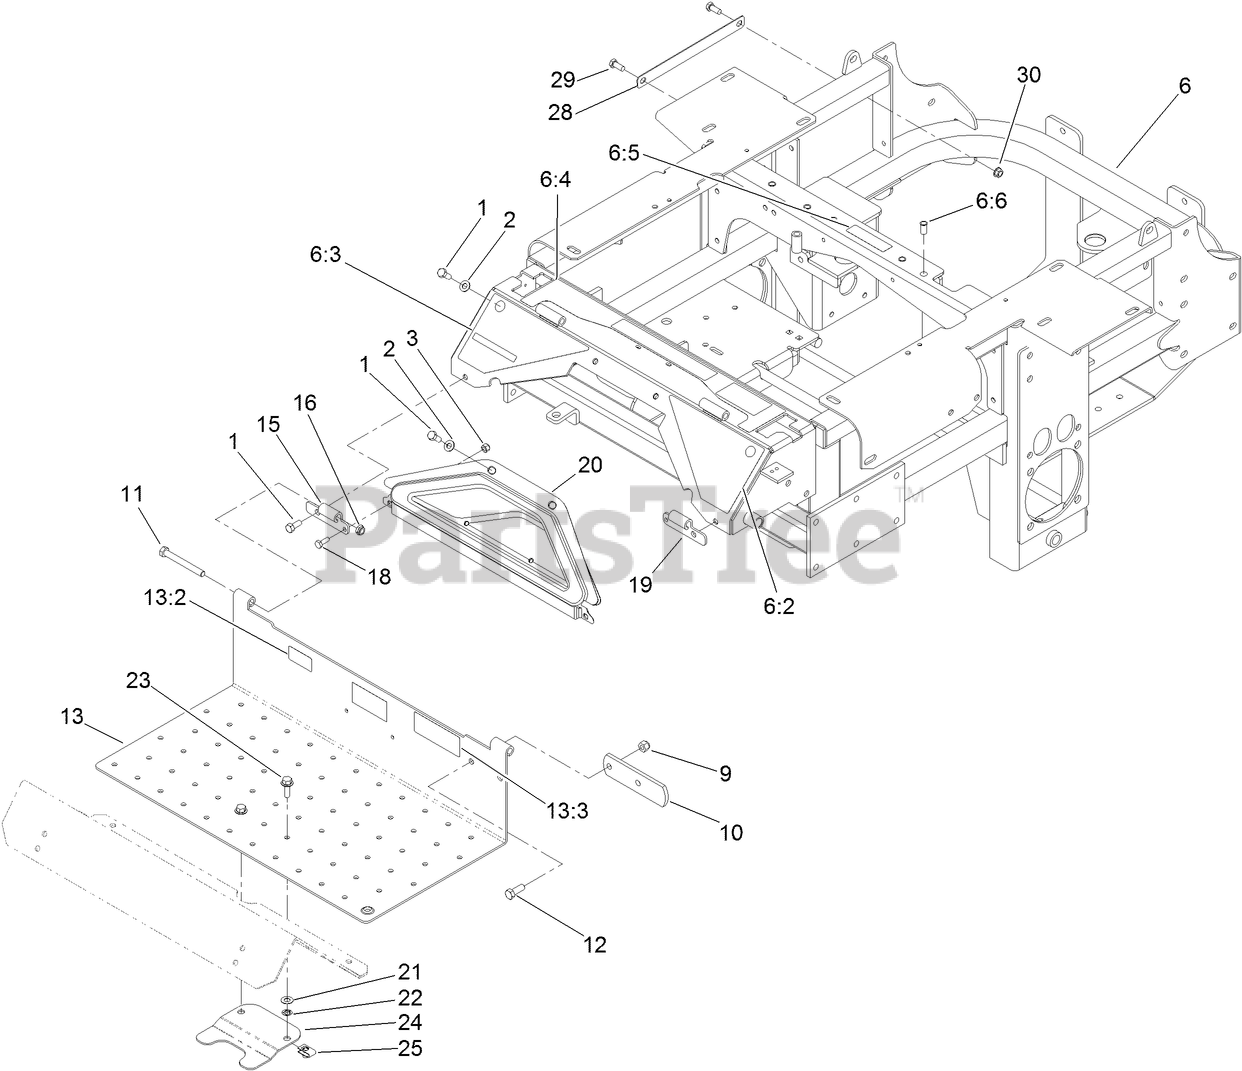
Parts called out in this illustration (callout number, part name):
1	SCREW-HH
2	WASHER-FLAT
3	NUT-LOCK, NI
6	TRACTION FRAME ASM
6:2	DECAL-DANGER, LEFT
6:3	DECAL-WARNING, RIGHT
6:4	DECAL-CONSOLE, TOP (CE)
6:5	DECAL-COVER, MISSING
6:6	NUT-CLINCH
9	NUT-LOCK, NI
10	STOP-BRAKE, PARK
11	SCREW-HH
12	SCREW-HH
13	FLOOR PAN ASM
13:2	DECAL-PROTECTION, EAR
13:3	DECAL-DIESEL, BIO-READY
15	HINGE-FLOORPAN, LH
18	SCREW-HH
19	HINGE-FLOORPAN, RH
20	POCKET
21	WASHER-THRUST
22	NUT-PUSH
23	SCREW-HHF
24	ADAPTER-CAPTIVE
25	NUT-U
29	SCREW-HH
30	NUT-HHF, WHIZ
